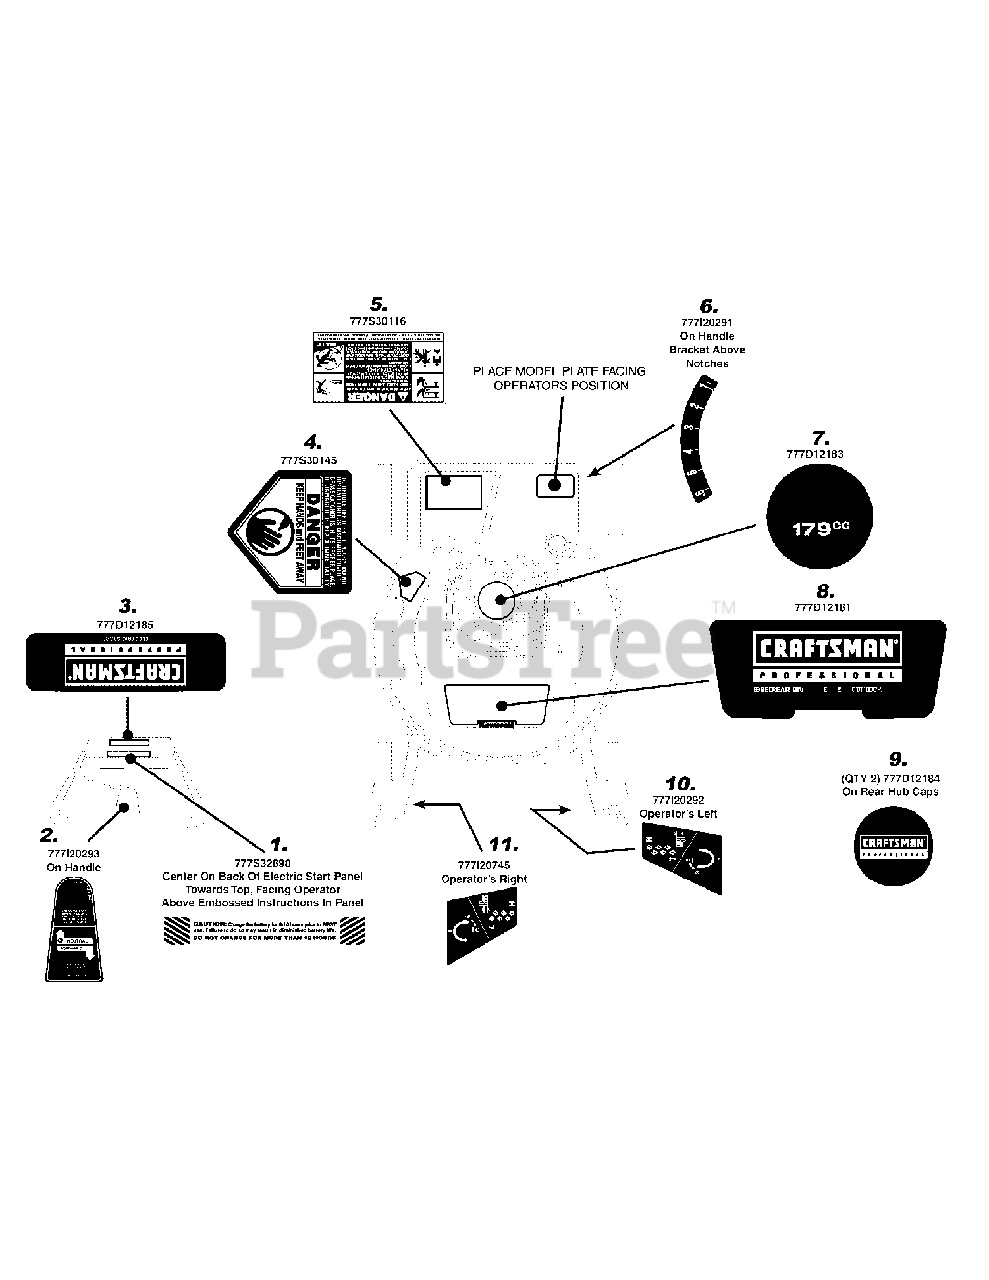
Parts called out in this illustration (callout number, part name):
1	LABEL-MOWER CHARGE CAUTION
2	LABEL-6SPD SELF PROPLD
3	LABEL-MOWER CRAFTSMAN PRO
4	LABEL
5	LABEL-MOWER DANGER
6	LABEL-HEIGHT ADJUS
7	LABEL-MOWER KAW ENGINE
8	LABEL-MOWER KAW ENGINE CRFTSMN PRO
9	LABEL-MOWER HUB CRAFTSMAN PRO
10	LABEL-CASTOR LOCK
11	LABEL-CASTOR LOCK
